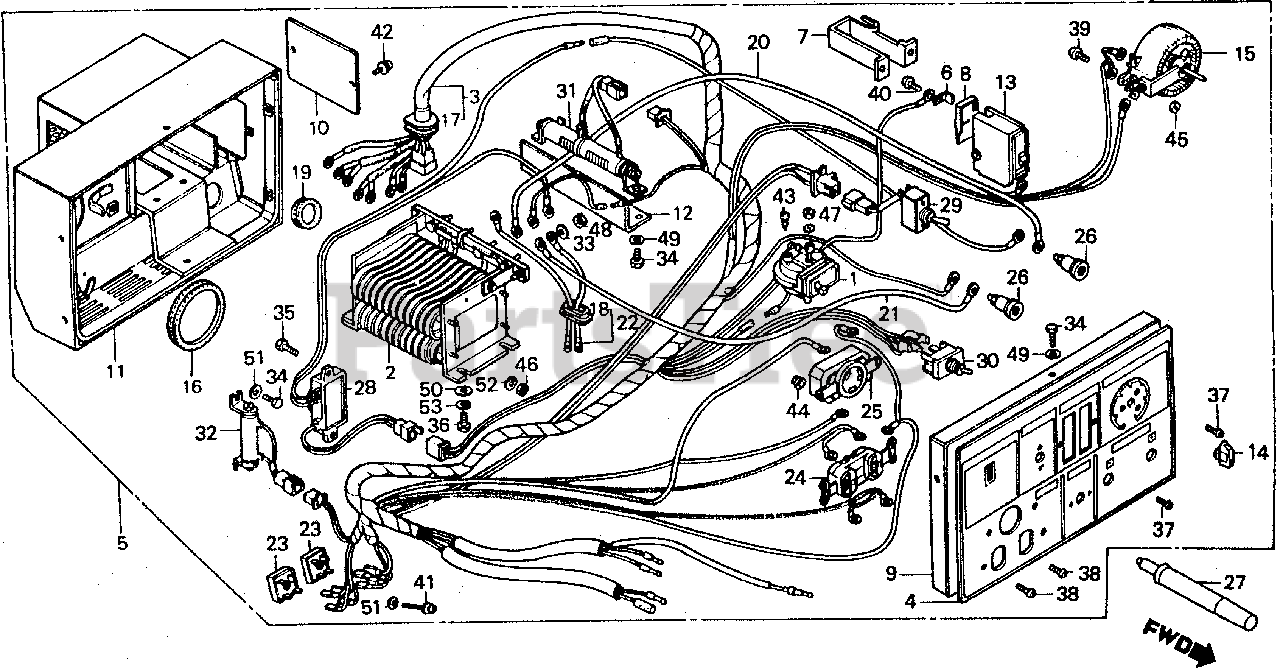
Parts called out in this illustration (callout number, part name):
1	SWITCH ASSY., UNIT
2	REACTOR ASSY.
3	WIRE HARNESS ASSY. (NOT AVAILABLE)
4	PLATE, CONTROL BOX A (N/A: SEE ASSEMBLY)
5	BOX ASSY., CONTROL *R8* (BRIGHT RED)
6	TERMINAL, BREAKER
7	SUPPORT, BREAKER
8	COVER, TERMINAL
9	PANEL, CONTROL *R8* (A) (BRIGHT RED) (NOT AVAILABLE)
10	PLATE, SIDE *R8* (BRIGHT RED)
11	CASE, CONTROL *R8* (BRIGHT RED)
12	PLATE, SEPARATOR
13	BREAKER, CIRCUIT (33.5A) (NOT AVAILABLE)
14	KNOB, ADJUSTING
15	RESISTOR, VARIABLE (NOT AVAILABLE)
17	GROMMET, A.C. WIRE
18	GROMMET, A.C. WIRE
19	GROMMET, MAIN WIRE
20	WIRE W, TERMINAL A (NOT AVAILABLE)
21	WIRE, TERMINAL
22	WIRE HARNESS ASSY., D.C.
24	RECEPTACLE ASSY. (125V-20A)
24	RECEPTACLE (20A/125V)
25	RECEPTACLE (3-PRONG) (30A/125V)
26	RECEPTACLE, PANEL
27	CONNECTOR, MALE
28	CONTROL UNIT ASSY., IDLE (NOT AVAILABLE)
29	SWITCH ASSY.
30	SWITCH ASSY.
31	RESISTOR, ADJUSTABLE
33	WASHER, SPRING (6MM)
34	BOLT, HEX. (4X10)
35	BOLT, HEX. (5X14)
36	BOLT, HEX. (8X20)
37	SCREW, PAN (4X6)
38	SCREW, PAN (4X8)
39	SCREW, PAN (4X10)
40	SCREW, PAN (5X12)
41	SCREW-WASHER (4X20)
42	SCREW-WASHER (4X10)
43	SCREW, TAPPING (5X10) (NOT AVAILABLE)
44	NUT, HEX. (4MM)
45	NUT, HEX. (4MM)
46	NUT, HEX. (5MM)
47	NUT, HEX. (5MM)
48	NUT, HEX. (6MM)
49	WASHER, PLAIN (4MM)
50	WASHER, PLAIN (8MM)
51	WASHER, PLAIN (4MM)
52	WASHER, SPRING (5MM)
53	WASHER, SPRING (8MM)
